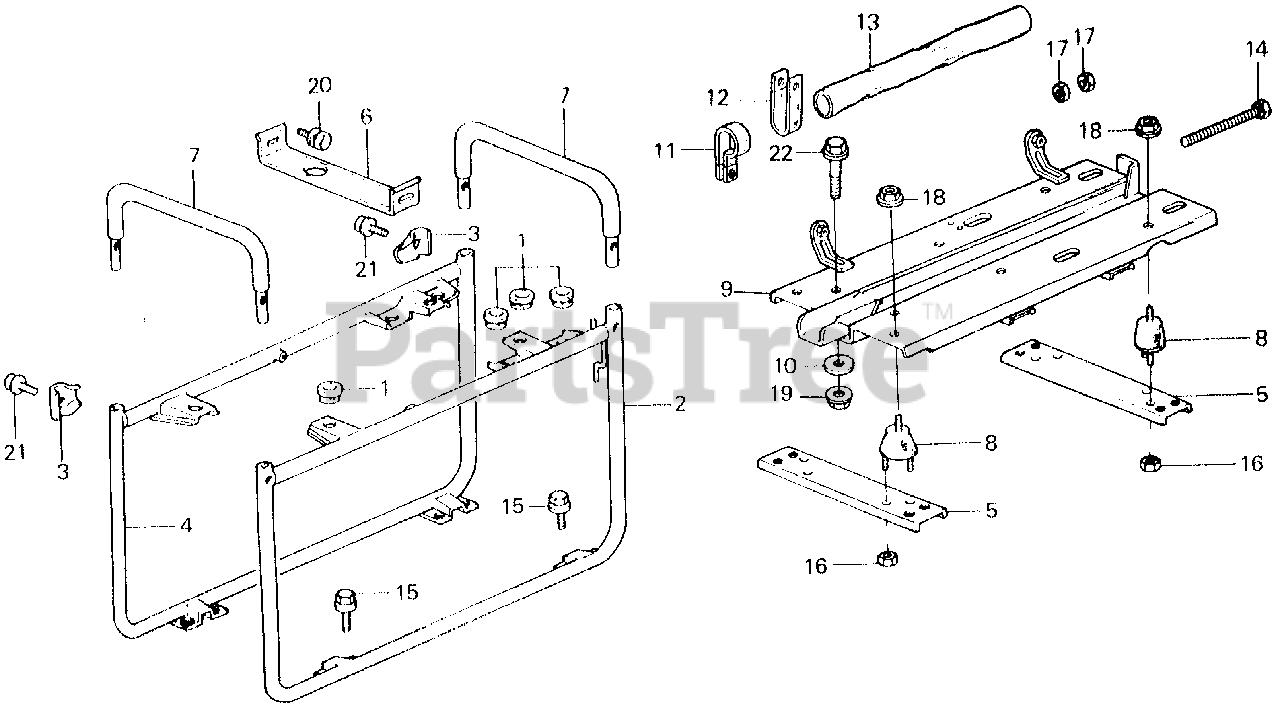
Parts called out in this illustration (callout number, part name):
1	RUBBER, TANK CUSHION
2	FRAME, FR. PIPE
3	PLATE, JOINT
4	FRAME, RR. PIPE
5	PLATE (LOWER)
6	STOPPER, ENGINE
7	HANDLEBAR (NOT AVAILABLE)
8	RUBBER, ENGINE SETTING
9	BED, ENGINE
10	WASHER, EX. MANIFOLD
11	CLIP, WIRE
11	CLIP, CORD
13	TUBE, WIRE
14	BOLT, HEX. (8X80)
15	BOLT-WASHER (8X16)
16	NUT, HEX. (6MM)
17	NUT, HEX. (8MM)
18	NUT, FLANGE (8MM)
19	NUT, FLANGE (10MM)
20	BOLT, FLANGE (6X12)
21	BOLT, FLANGE (8X16)
22	BOLT, FLANGE (10X50)
